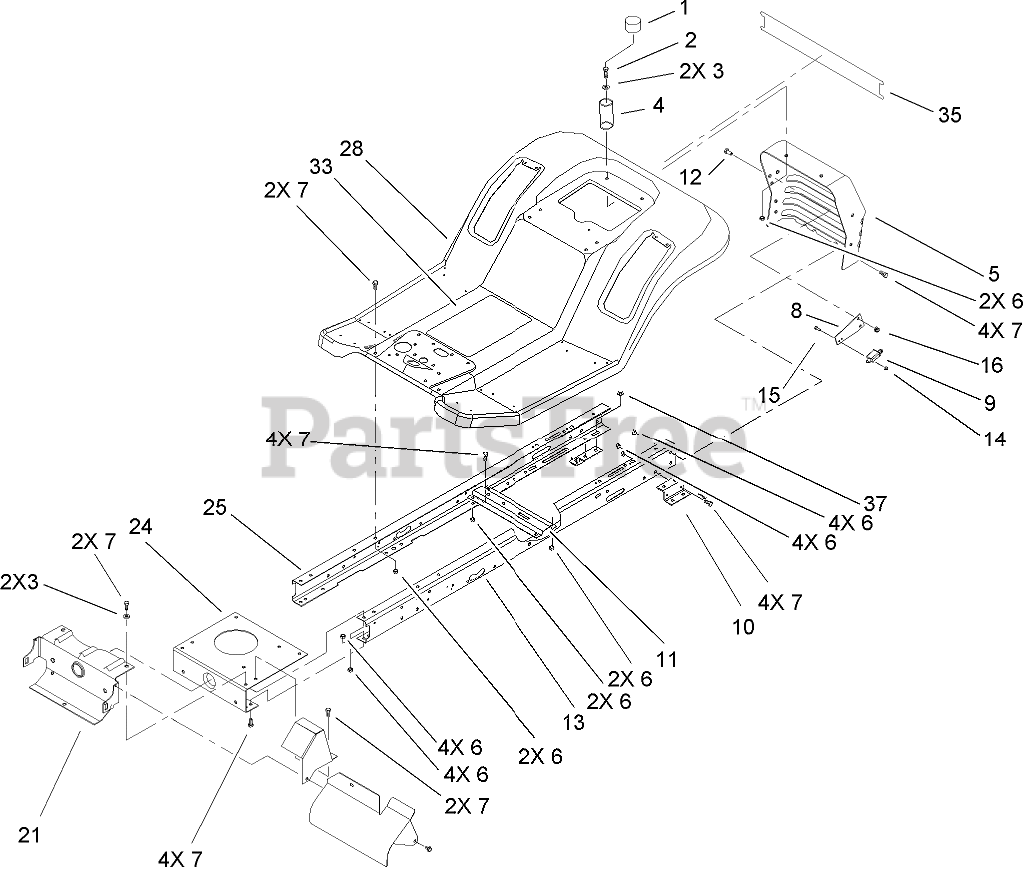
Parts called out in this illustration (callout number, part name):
1	CAP-PROTECTOR
2	SCREW-HH
3	WASHER-PLAIN
4	SPRING-COMPRESSION
5	SUPPORT-SEAT/REAR HITCH
6	NUT-LOCK, NI
7	SCREW-HH
8	PLATE-SWITCH
9	SWITCH-POLE, SINGLE
10	BRACKET-MOUNTING, TRANSMISSION
11	BRACKET-IDLER PIVOT
12	SCREW-HH
13	RAIL-FRAME, LH
14	NUT-LOCK
15	SCREW-SHH
16	NUT-LOCK, NI
21	SUPPORT-FRONT, AXLE
24	PLATE-MOUNTING, ENGINE
25	RAIL-FRAME, RH
28	REAR BODY ASM
33	DECAL-INSTRUCTION
35	DECAL-REAR FENDER, LAWN TRACTORS
37	WASHER-PLAIN
